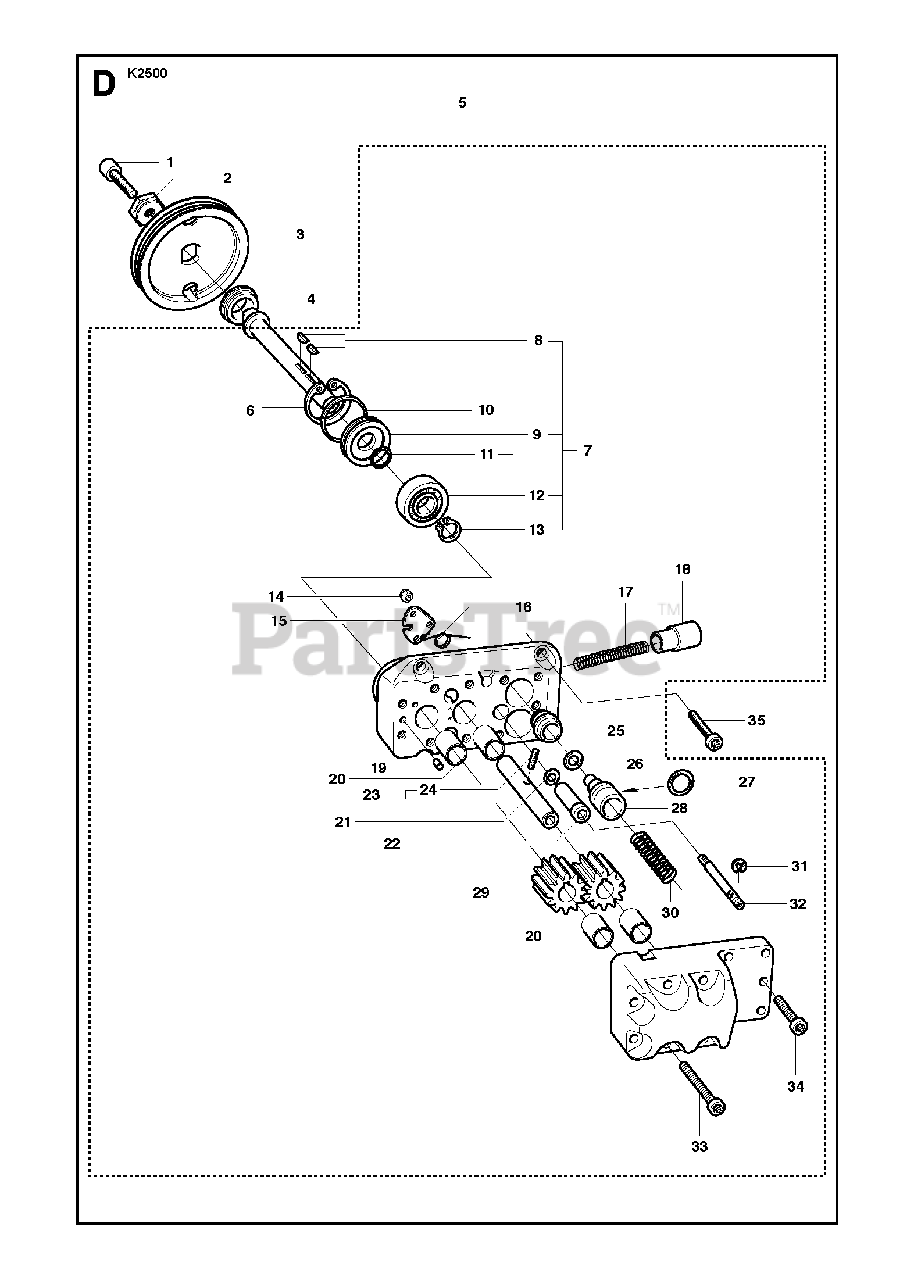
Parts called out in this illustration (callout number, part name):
1	SCREW ITXSCMNew Part
2	SPACING SLEEVENew Part
8	WOODRUFF KEY
14	HEXAGON LOCKING NUT
19	GUIDE BUSHING
33	SCREW ITXSCMNew Part
34	SCREW ITXSCMNew Part
35	SCREW ITXSCMNew Part
